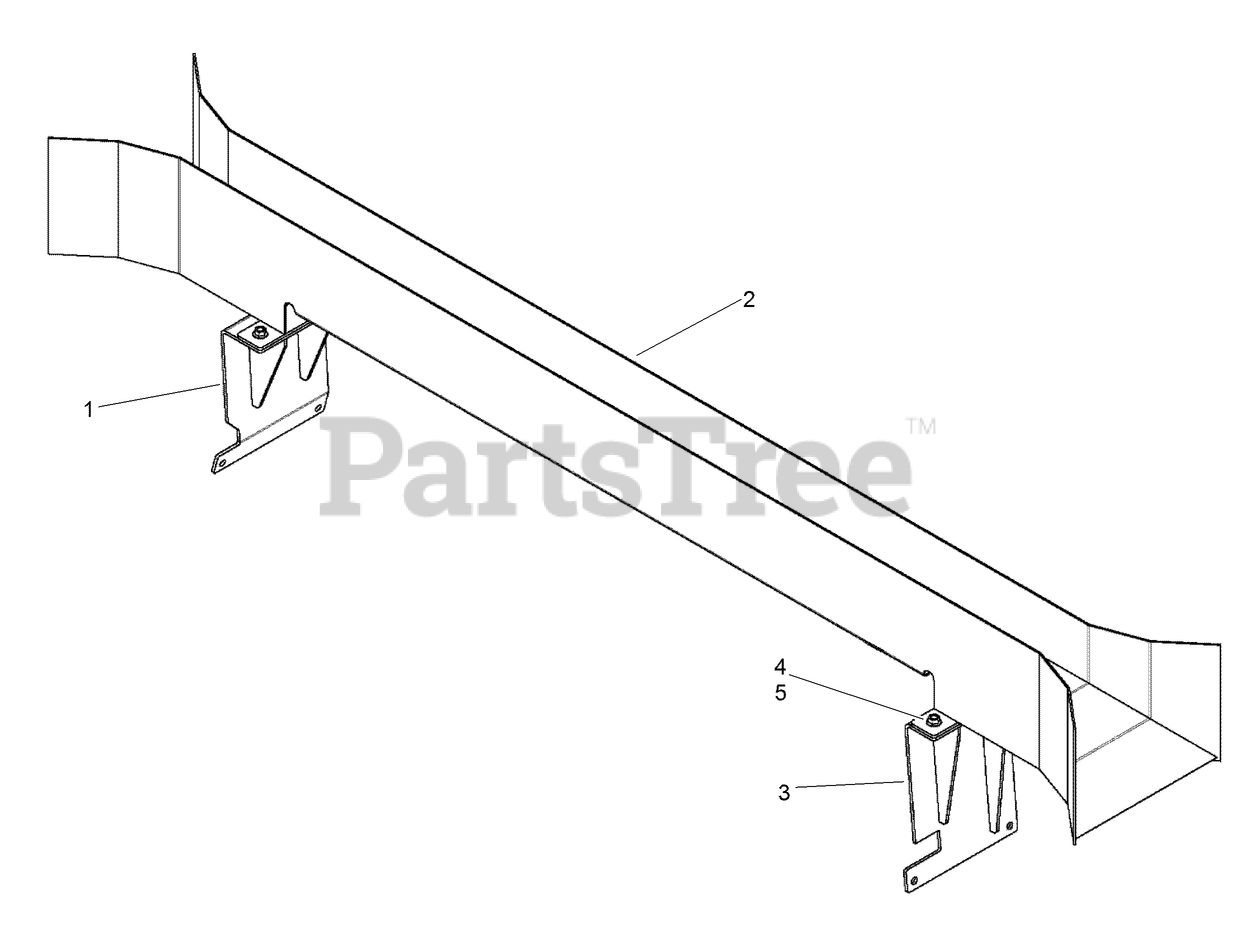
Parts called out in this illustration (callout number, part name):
1	WELDMENT - Front Cable Chute Bracket
2	WELDMENT - Cable Chute
3	WELDMENT - Rear Bracket
4	SCREW-FLANGE
5	NUT-FLANGE, NYLOCK
